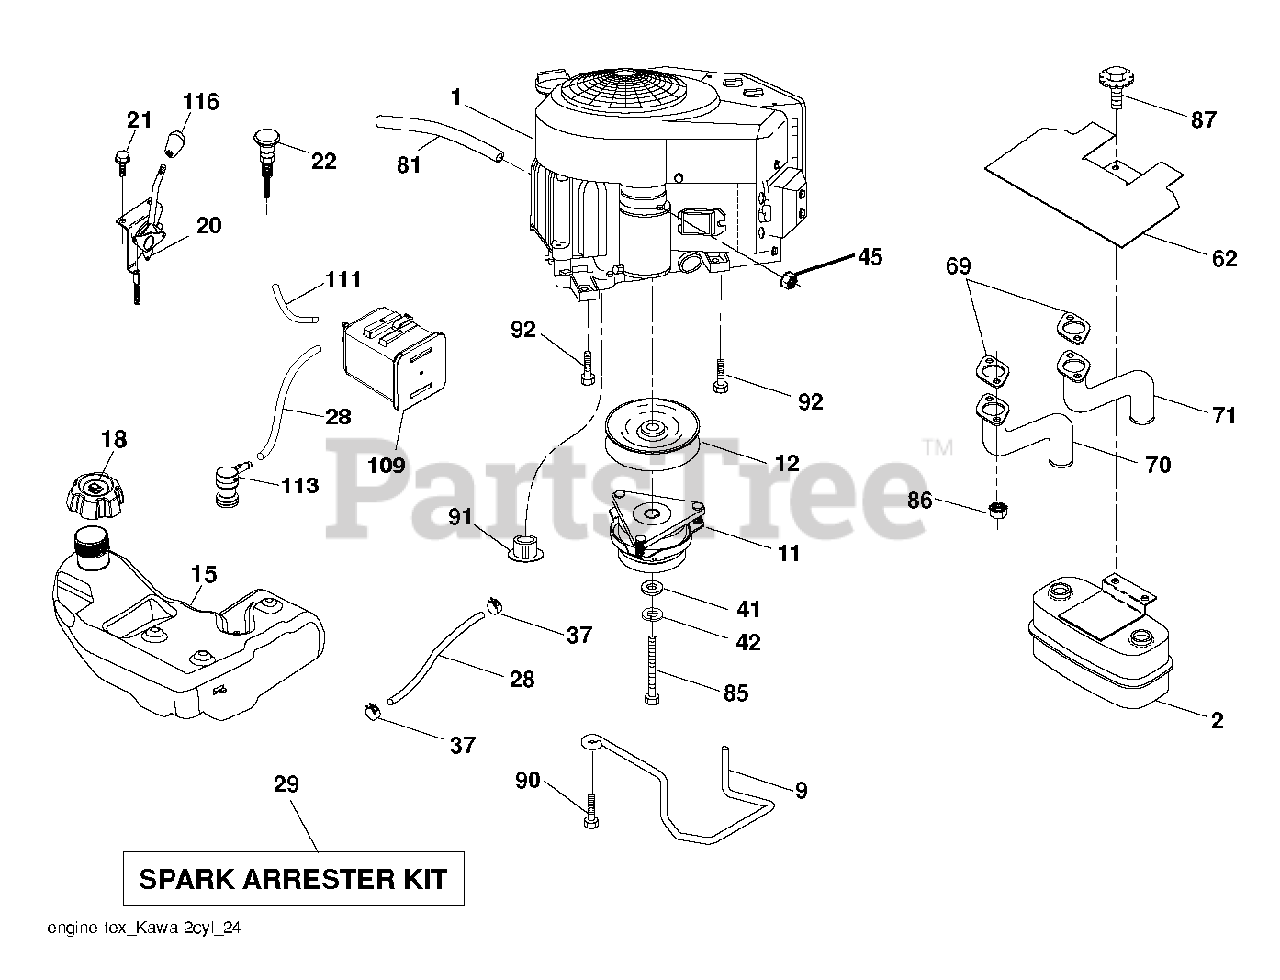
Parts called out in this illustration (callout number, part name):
2	MUFFLER.ASM.TWN.EXTNDED.DFLCTR
9	KEEPER BELT ENGINE
11	RB.CLUTCH.OGURA.4.4.PD
12	PULLEY.ENGINE.TUFFTORQ
15	TANK.ASM.FUEL.3GA.CARB
18	CAP.ASM.FL.RITCH.3"E10.SYM.498
20	CONTROL.THROTTLE.PRO.
21	SCREW.#10 X 0.750.BOS
22	CONTROL, CHOKE
28	LINE.FUEL.64"REAR.EMIS
29	KIT.SPARK ARRESTOR 794945 B&S
37	HOSE CLAMP
42	LOCKWASHER
45	NUT
62	SHIELD.HEAT.MUFFLER
70	TUBE.EXHAUST.LH.FR961/FR730
71	TUBE.EXHAUST.RH.FR961/FR730
81	TUBE, DRAIN OIL ASM.
85	BOLT HEX 7/16-20X4-1/4"
86	NUT.HEX.FLANGE.TOPLOCK
87	BOLT, 5/16-18 X 1 3/4
90	SCREW 3/8-16X1
91	BUSHING.1.375OD
92	SCREW 3/8-16X1
109	CANNISTER, CARBON
111	RP PURGE LINE
113	VALVE.SLANT.CARTRDG.90 DEG.TEX
116	KNOB - SHIFT
